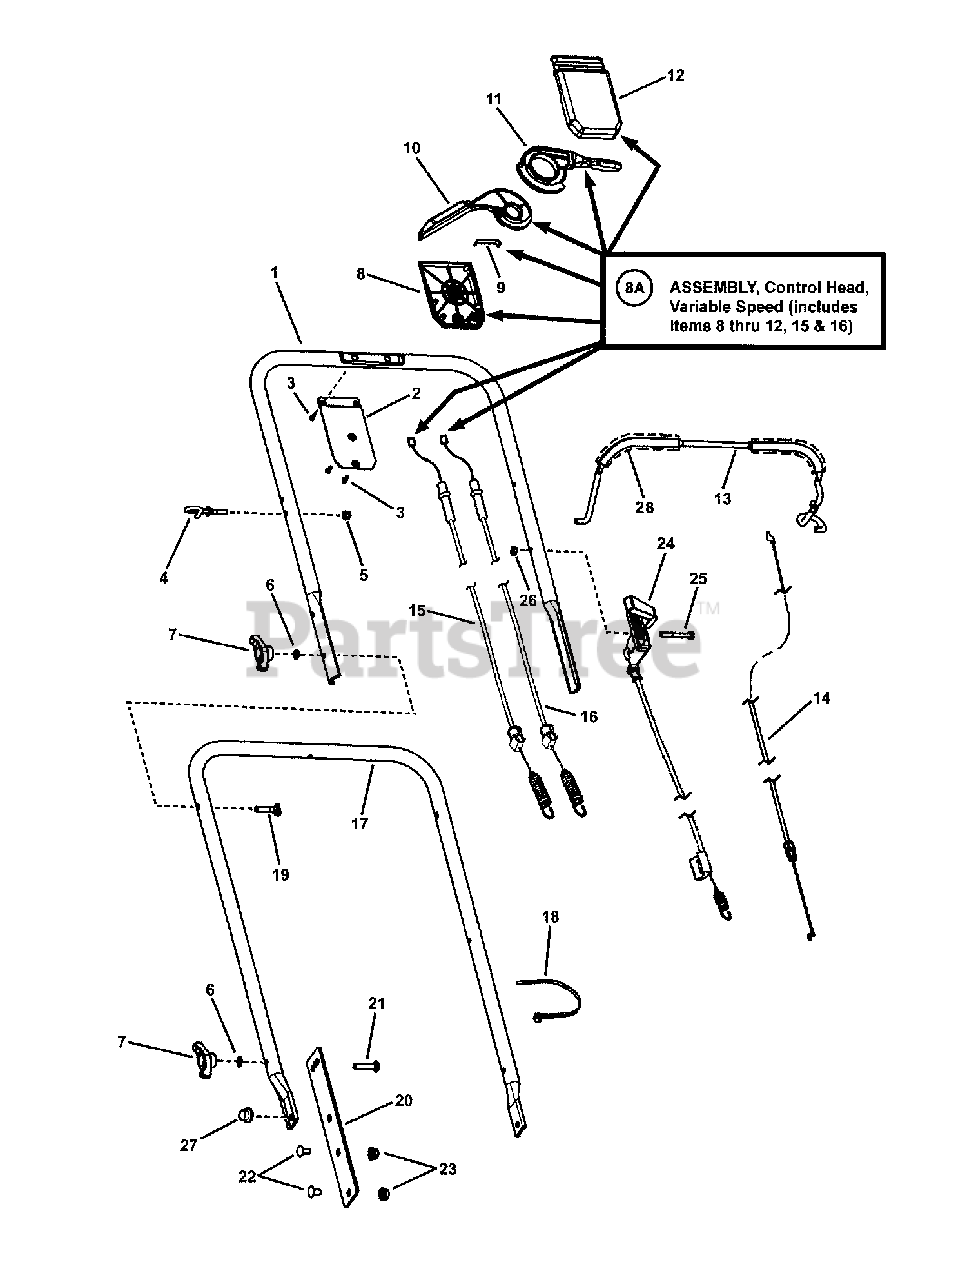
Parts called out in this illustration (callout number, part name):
1	HANDLE, Upper
2	PLATE, Control Panel
3	SCREW, #8-16 Recessed Pan Head (Torxplus)
4	GUIDE, Rope
5	NUT, 1/4-20 Hex Nyloc
6	WASHER, 5/16 Internal Tooth Lock
7	KNOB, 5/16-18 Wing (Black)
8	CASE HALF, Bottom, Black
8A	ASSY, Control Head Variable Speed (Incl. 8, 9, 10, 11, 12, 15 & 16)
9	SPRING STEEL
10	CLUTCH LEVER, Silver
11	ASSEMBLY, Speed Lever/Friction Material
12	CASE HALF, Top, Variable Speed- Black
13	BAIL, Brake
14	* CABLE, Zone Control
15	* CABLE, Clutch
16	* CABLE, Speed
17	HANDLE, Lower
18	WIRE TIE, 11 Inch Black Nylon
19	BOLT, 5/16-18 x 2" Curved Head Square Neck GR 2
20	BRACKET, Lower Handle
21	BOLT, 5/16-18 x 1-1/2" Round Head Square Neck, GR 5
22	BOLT, 5/16-18 x 5/8" Round Head Short Square Neck Carriage
23	NUT, 5/16-18 Hex Flange Lock
24	* CONTROL, Swivel Wheel Latch 56.5 (LH Outside)
25	SCREW, 1/4-20 x 2" Hex Head Cap, GR 5
26	NUT, 1/4-20 Hex Center Lock
27	PUSHNUT, 3/8"
28	FOAM GRIP, 7"
